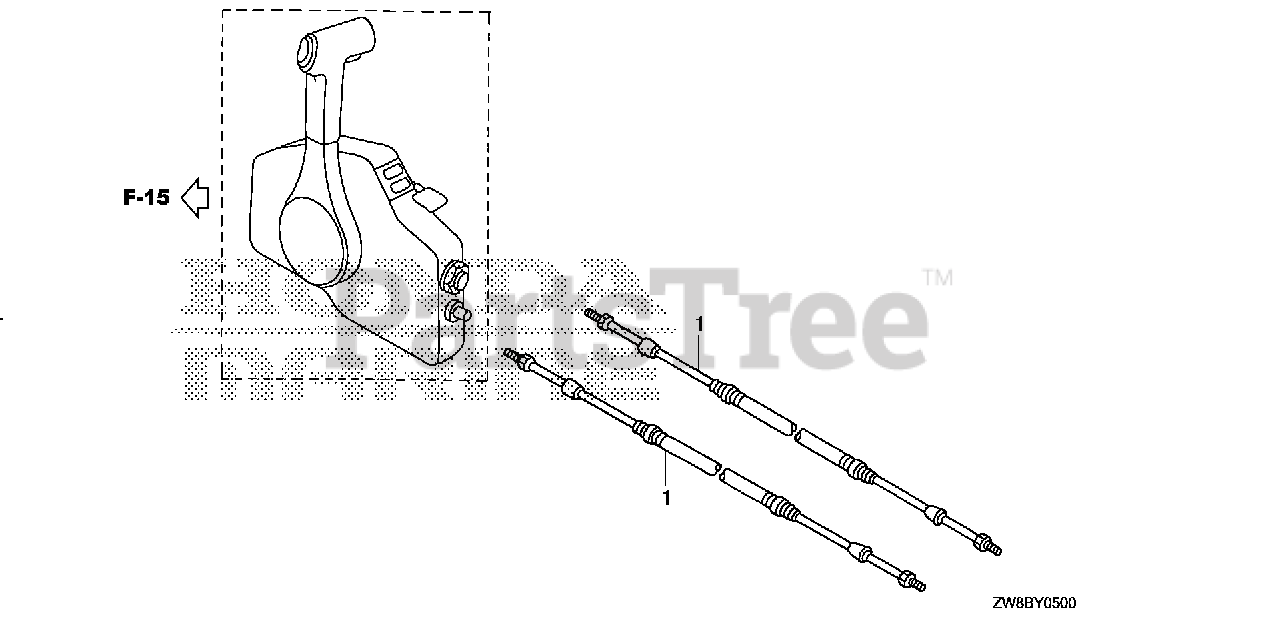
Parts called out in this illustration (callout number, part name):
1	CABLE, REMOTE CONTROL (10') (LOW FRICTION)
1	CABLE ASSY., PUSH-PULL (33C-5FT)
1	CABLE, REMOTE CONTROL (11') (LOW FRICTION)
1	CABLE ASSY., PUSH-PULL (33C-6FT)
1	CABLE, REMOTE CONTROL (12') (LOW FRICTION)
1	CABLE ASSY., PUSH-PULL (33C-7FT)
1	CABLE, REMOTE CONTROL (13') (LOW FRICTION)
1	CABLE ASSY., PUSH-PULL (33C-8FT)
1	CABLE, REMOTE CONTROL (14') (LOW FRICTION)
1	CABLE ASSY., PUSH-PULL (33C-9FT)
1	CABLE, REMOTE CONTROL (15') (LOW FRICTION)
1	CABLE ASSY., PUSH-PULL (33C-10FT)
1	CABLE, REMOTE CONTROL (16') (LOW FRICTION) (NOT AVAILABLE)
1	CABLE ASSY., PUSH-PULL (33C-11FT)
1	CABLE, REMOTE CONTROL (17') (LOW FRICTION)
1	CABLE ASSY., PUSH-PULL (33C-12FT)
1	CABLE, REMOTE CONTROL (18') (LOW FRICTION) (NOT AVAILABLE)
1	CABLE ASSY., PUSH-PULL (33C-13FT)
1	CABLE, REMOTE CONTROL (19') (LOW FRICTION)
1	CABLE ASSY., PUSH-PULL (33C-14FT)
1	CABLE, REMOTE CONTROL (20') (LOW FRICTION) (NOT AVAILABLE)
1	CABLE ASSY., PUSH-PULL (33C-15FT)
1	CABLE, REMOTE CONTROL (21') (LOW FRICTION)
1	CABLE ASSY., PUSH-PULL (33C-16FT)
1	CABLE, REMOTE CONTROL (22') (LOW FRICTION) (NOT AVAILABLE)
1	CABLE ASSY., PUSH-PULL (33C-17FT)
1	CABLE, REMOTE CONTROL (23') (LOW FRICTION)
1	CABLE ASSY., PUSH-PULL (33C-18FT)
1	CABLE, REMOTE CONTROL (24') (LOW FRICTION) (NOT AVAILABLE)
1	CABLE ASSY., PUSH-PULL (33C-19FT)
1	CABLE, REMOTE CONTROL (25') (LOW FRICTION)
1	CABLE ASSY., PUSH-PULL (33C-20FT)
1	CABLE, REMOTE CONTROL (26') (LOW FRICTION)
1	CABLE ASSY., PUSH-PULL (33C-21FT)
1	CABLE, REMOTE CONTROL (27') (LOW FRICTION)
1	CABLE ASSY., PUSH-PULL (33C-22FT)
1	CABLE, REMOTE CONTROL (28') (LOW FRICTION) (NOT AVAILABLE)
1	CABLE ASSY., PUSH-PULL (33C-23FT)
1	CABLE, REMOTE CONTROL (29') (LOW FRICTION)
1	CABLE ASSY., PUSH-PULL (33C-24FT)
1	CABLE, REMOTE CONTROL (30') (LOW FRICTION) (NOT AVAILABLE)
1	CABLE ASSY., PUSH-PULL (33C-25FT)
1	CABLE, REMOTE CONTROL (31') (LOW FRICTION)
1	CABLE ASSY., PUSH-PULL (33C-26FT)
1	CABLE, REMOTE CONTROL (32') (LOW FRICTION) (NOT AVAILABLE)
1	CABLE ASSY., PUSH-PULL (33C-27FT)
1	CABLE, REMOTE CONTROL (33') (LOW FRICTION)
1	CABLE ASSY., PUSH-PULL (33C-28FT)
1	CABLE, REMOTE CONTROL (34') (LOW FRICTION) (NOT AVAILABLE)
1	CABLE ASSY., PUSH-PULL (33C-29FT)
1	CABLE, REMOTE CONTROL (35') (LOW FRICTION)
1	CABLE ASSY., PUSH-PULL (33C-30FT)
1	CABLE ASSY., PUSH-PULL (33C-31FT)
1	CABLE ASSY., PUSH-PULL (33C-32FT)
